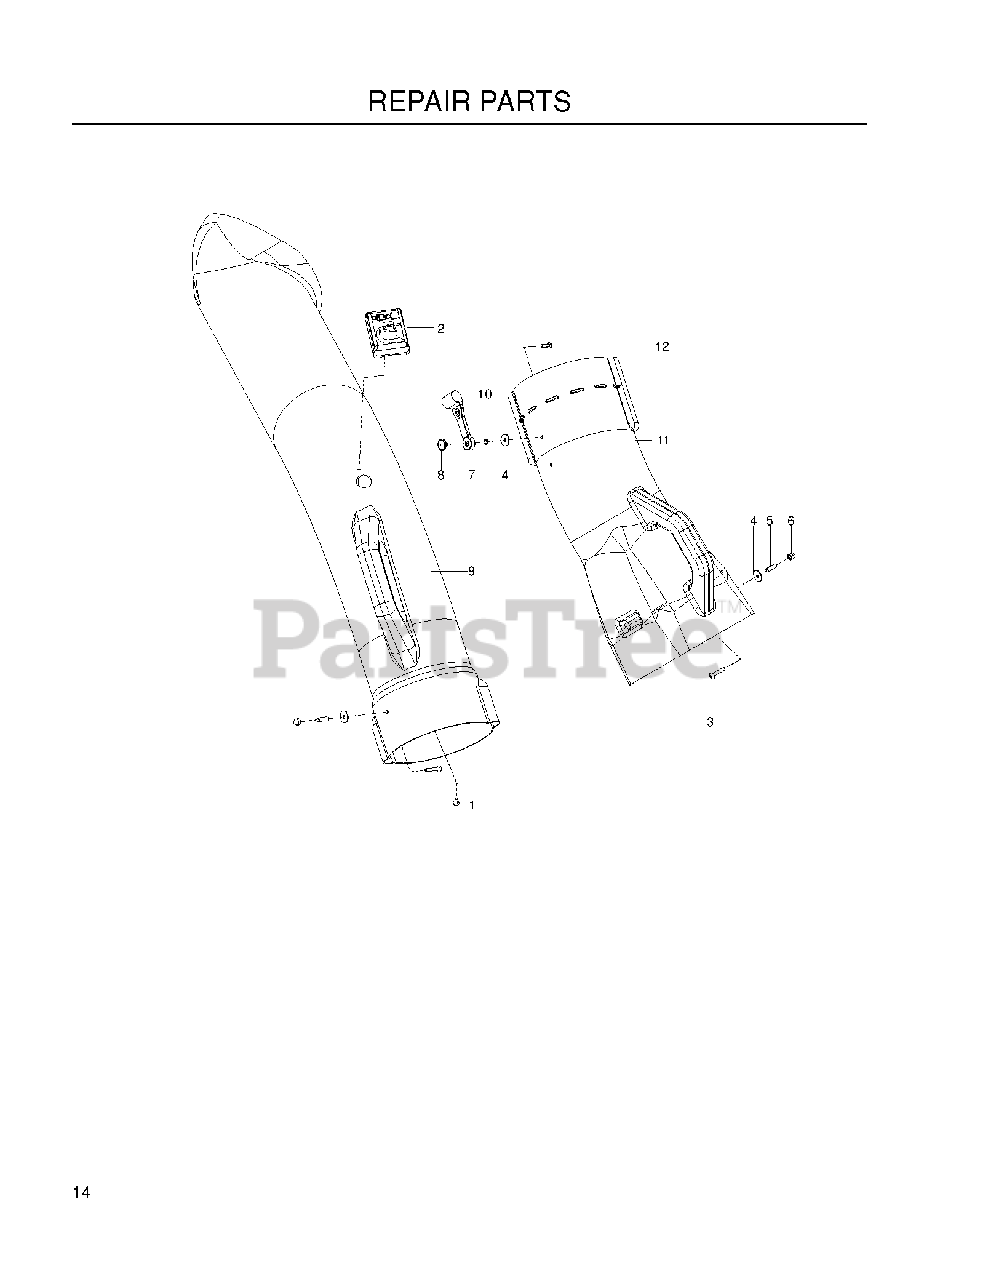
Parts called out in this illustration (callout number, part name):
1	SCREW
2	DUMP BAG INDICATOR
3	SCREW #10-24 X 1-1/8 ZD SPEC
5	BSHG .202X.75 LG SPLIT ZD SPEC
6	NUT 10-24 ACORN ZD
7	HOOD LATCH
8	NUT 10-24 WELD PLATED
9	CHUTE, UPPER - TRIMMED
10	WASHER - 3/16 LOCK ZD
11	CHUTE, MIDDLE
12	SCREW #10-24 X 5/8
